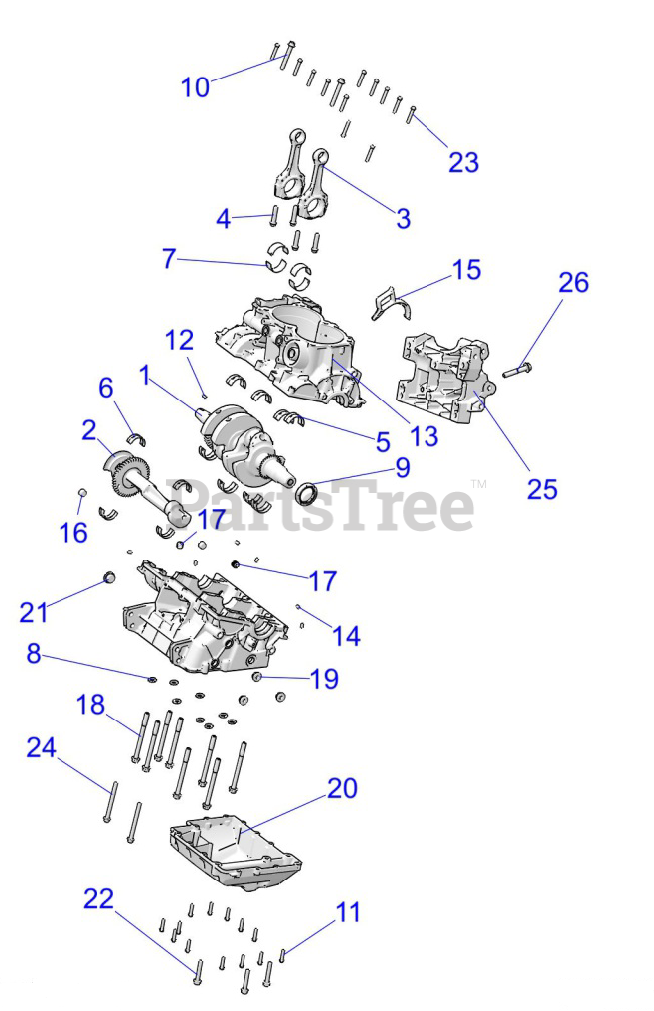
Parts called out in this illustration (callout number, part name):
1	ASM-CRANKSHAFT
2	ASM-BALANCE SHAFT
3	ASM-CONNECTING ROD
3	ASM-CONNECTING ROD,CLN
4	SCR-ROD-MJ9X1X40-4H6H-12.9
5	BEARING- MAIN- BLUE
5	BEARING- MAIN- GREEN
5	BEARING- MAIN- YELLOW
5	BEARING- MAIN- RED
6	BEARING, CONNECTING ROD, WHITE
6	BEARING- CONNECTING ROD- BLUE
6	BEARING- CONNECTING ROD- GREEN
6	BEARING, CONNECTING ROD, YELLOW
7	BEARING-BAL SHAFT-38X41X17.5
8	WASHER
9	SEAL-CRANKSHAFT
10	SCR-HXFLG-M8X1.25X60
11	SCR-HXFLG-M6X1.0X25-10.9
12	KEY-WOODRUFF
13	ASM-CRANKCASE
14	PIN, DOWEL
15	DIVERTER, OIL DRAIN
16	PLUG-3/8 NPT,HX/SOC W/SEALANT
17	PLUG-HEX SOCKET-1/4X18-SEALANT
19	PLUG-HEX SCKT-W/O-RING-M16X1.5
20	COVER, SUMP
21	PLUG-HEX SCKT-W/O-RING-M20X1.5
22	SCR-M8X1.25X50 HX/FL-Y
23	SCR-HXFL-M6X1.0X35 8.8 ZY3
24	SCR-HXFLG-M8X1.25X90
25	BRKT-TRANSJOINT,MACH
26	SCR-HXFL-M10X1.5X60 8.8 ZY P80
